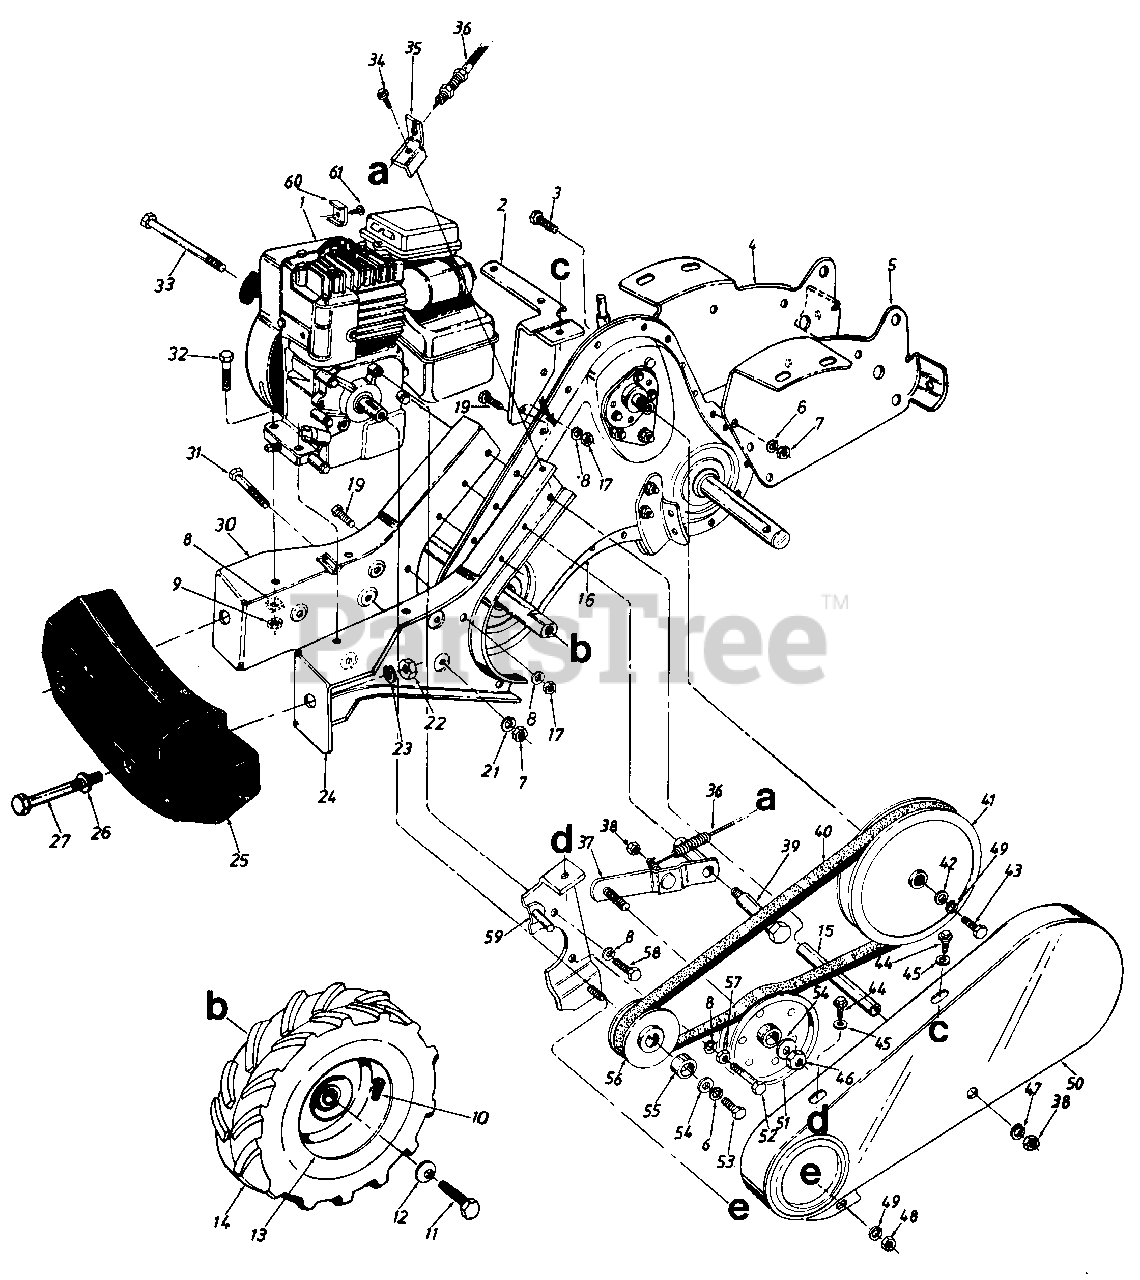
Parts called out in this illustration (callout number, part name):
1	Engine
4	Tine Shield Mtg. Brkt.-R.H.
7	Hex Nut 3/8-16 Thd.
8	L-Wash. 5/16" l.D.
9	Hex Nut 5/16-18" Thd.
10	Air Valve
11	Hex Bolt 5/16-24 x .62" Lg.
12	Bell-Wash. .345" I.D. x .88"
13	Wheel Rim Ass'y. Only
14	L.H. Wheel Ass'y. Comp.
14	R.H. Wheel Ass'y. Comp.
14	Tire Only 13 x 5.0
15	Spacer 3/8" I.D. x 3.38" Lg.
16	Transmission Comp.
17	Hex Nut 5/16-18 Thd.
19	Hex Bolt 5/16-18 x .75" Lg.
21	L-Wash. 3/8" l.D.-H.D.
22	Hex Nut 1/2-13 Thd .
23	L-Wash. 1/2" I.D. *
26	Fl-Wash. .510" I.D. x 1.0"
27	Hex Bolt 1/2-13 x 5.00" Lg.
32	Hex Bolt 5/16-18 x 1.50"
33	Hex Bolt 5/16-18 x 4.75" Lg.-Gr. 2
34	Hex Wash. TT-Tap Scr. 5/16-18 x .62" Lg.
35	Bracket Clutch Cable
36	Clutch Control Cable 53" Lg.
39	Shld. Bolt 500" Dia. x 2.27"
40	V-Belt
41	V-Pulley Split 5/8" I.D.
42	Fl-Wash. 1/4" I.D. x 93" O.D.
43	Hex Bolt 1/4-28 x .75" Lg.
44	Hex Wash. Hd. S-Tap Scr. 1/4-20 x .50" Lg.
45	Fl-Wash. .281" l.D. x .625"
46	Hex Cent. L-Nut 3/8-24 Thd.
47	Fl-Wash. 5/16" I.D.
48	Hex Nut 1/4-20 Thd.*
49	L-Wash. 1/4" I.D.*
51	Fl-ldler w/Flanges 3.75" O.D.
52	Hex Bolt 5/16-24 x 1.75n*
53	Hex Bolt 3/8-24 x 1.00n Lg.*
54	Fl-Wash. 3/8" I.D. x 1.00"
55	Spacer .758" l.D x 990"
56	Engine Pulley
57	Hex Nut 5/16-24 Thd.*
58	Hex Bolt 5/16-24 x .62" Lg.*
61	Hex Sems Scr. #10-32 x .62
